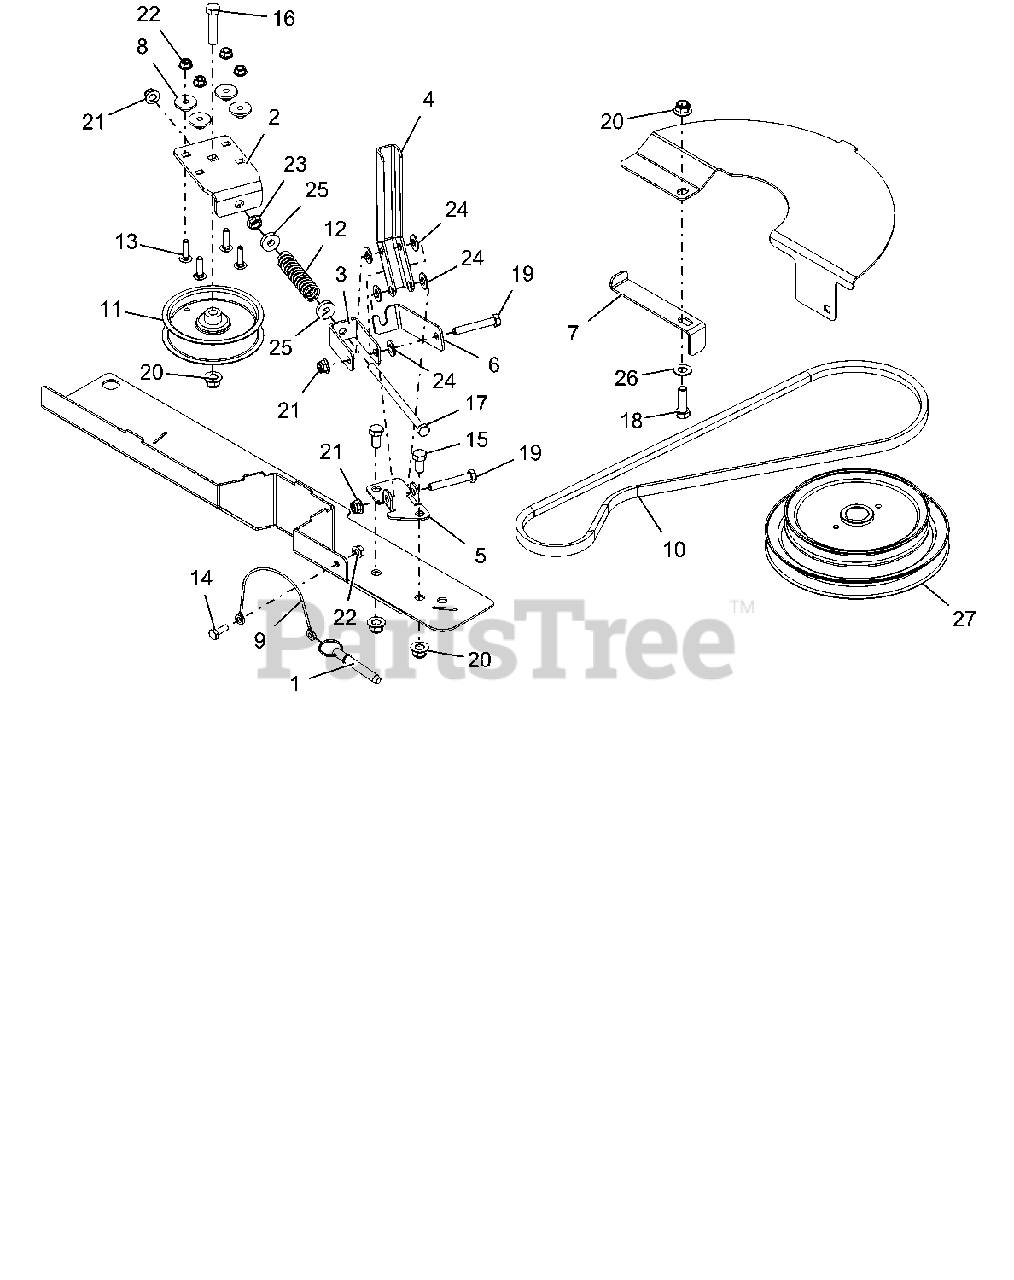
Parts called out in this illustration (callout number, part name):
1	PIN, SPRING BALL .375 OD X 1.50
2	BRKT, ADJUSTABLE IDLER
3	LINK, IDLER RELEASE-BLACK
4	LEVER, IDLER RELEASE-BLACK
5	MOUNT, IDLER RELEASE LEVER-BLK
6	LOCK, IDLER RELEASE LEVER-BLACK
7	FINGER, BELT-BLACK
8	BSHG, FLG .265 X .477 X .375 X 1.00
9	LANYARD, 12"
10	V-Belt, HA-WRAPPED CLUTCHING (NO RUBBER BLEED THRU)
11	PULLEY, IDLER 4.00 X .375
12	SPRG, COMPRESSION
13	BLT-RDHDSQNK .25-20X1.00 G5 YWZC
14	BLT-HEX .25-20X.75 GR5 YWZC
15	BLT-HEX .38-16X.75 GR5 YWZC
16	BLT-HEX .38-16X1.75 GR5 YWZC
17	BLT-HEX .31-18X5.50 GR5 YWZC
18	BLT-HEX .38-16X1.25 GR5 YWZC
19	BLT-HEX .31-18X2.00 GR5 YWZC
20	NUT-LK-NYL-FLG .38-16 YWZC
21	NUT-LK-NYL-FLG .31-18 YWZC
22	NUT, LK-TOP-FLG .25-20 YWZC
23	@NUT-SPNLK-FLG .312-18 YWZC
24	WSHR-FL-NYL .375X.75X.060
25	WSHR-FL-STL .328X.87X.179 YWZC
26	WSHR-FL-STL.406X.812X.065 YWZ
27	SHEAVE, DOUBLE 1.000" ID X 8.250" & 6.500" OD
